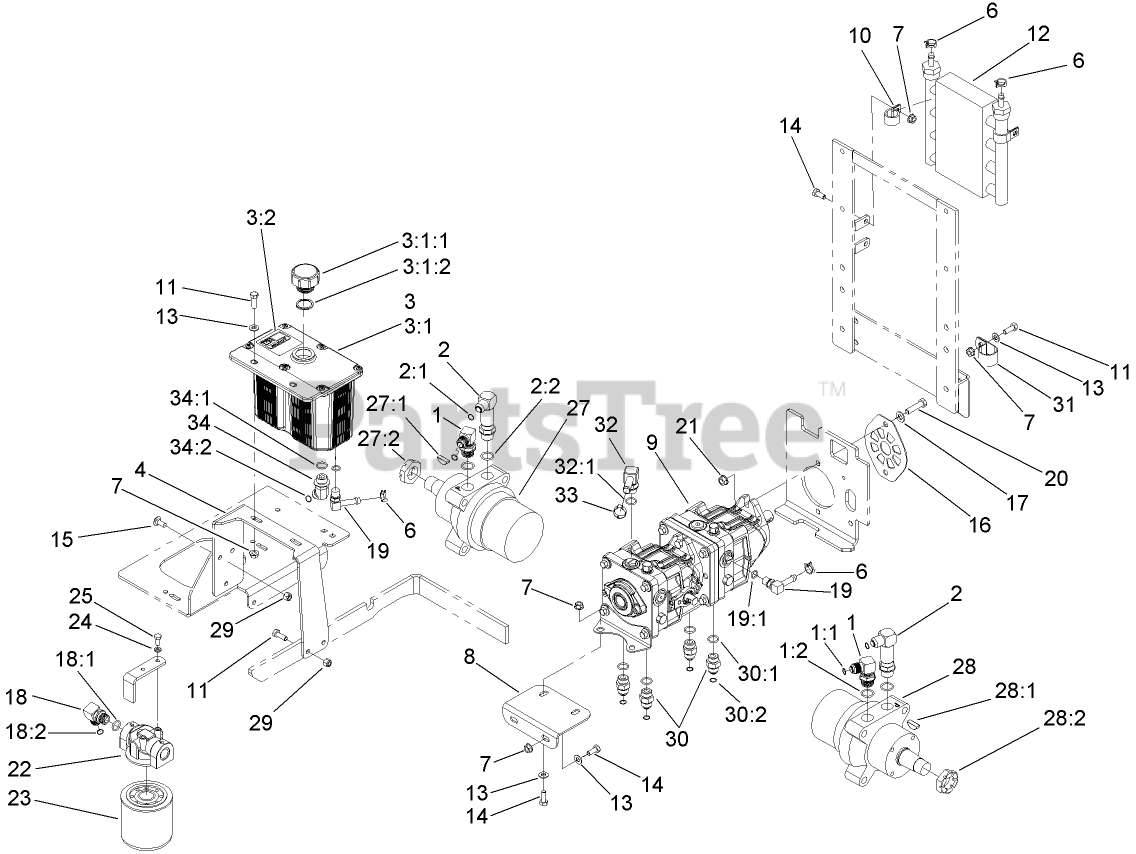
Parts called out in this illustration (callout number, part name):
1	FITTING-HYD, 90 DEG
1:1	O-Ring
1:2	O-RING
2	FITTING-ELBOW-90
2:1	O-Ring
2:2	O-RING
3	HYDRAULIC TANK ASM
3:1	TANK-HYDRAULIC
3:1:1	CAP-RESERVOIR, HYD
3:1:2	GASKET-CAP
3:2	DECAL-TANK, HYD
4	BRACKET-TANK, HYDRAULIC
6	CLAMP-HOSE
7	NUT-HF
8	BRACKET-PUMP, FRONT
9	TANDEM PUMP ASM
10	R-CLAMP
11	SCREW-HH
12	COOLER-OIL, HYDRO
13	WASHER-PLAIN
14	SCREW-HH
15	SCREW-CARR
16	PLATE-SHIELD, PUMP
17	WASHER-FLAT
18	FITTING-90 DEG
18:1	O-RING
18:2	O-Ring
19	FITTING-ELBOW, 90
19:1	O-Ring
20	SCREW-HH
21	NUT-HHF, WHIZ
22	HEAD-FILTER
23	CARTRIDGE-FILTER, OIL
24	WASHER-LOCK
25	SCREW-HH
27	MOTOR-WHEEL, CW
27:1	KEY-WOODRUFF
27:2	NUT-HH
28	MOTOR-WHEEL, CCW
28:1	KEY-WOODRUFF
28:2	NUT-HH
29	NUT-LOCK, NI
30	FITTING-STRAIGHT
30:1	O-RING
30:2	O-Ring
31	CLAMP-R
32	FITTING-ELBOW, 90 DEG
32:1	O-RING
33	CLAMP-HOSE
34	FITTING-HYD, 45 DEG
34:1	O-RING
34:2	O-Ring
